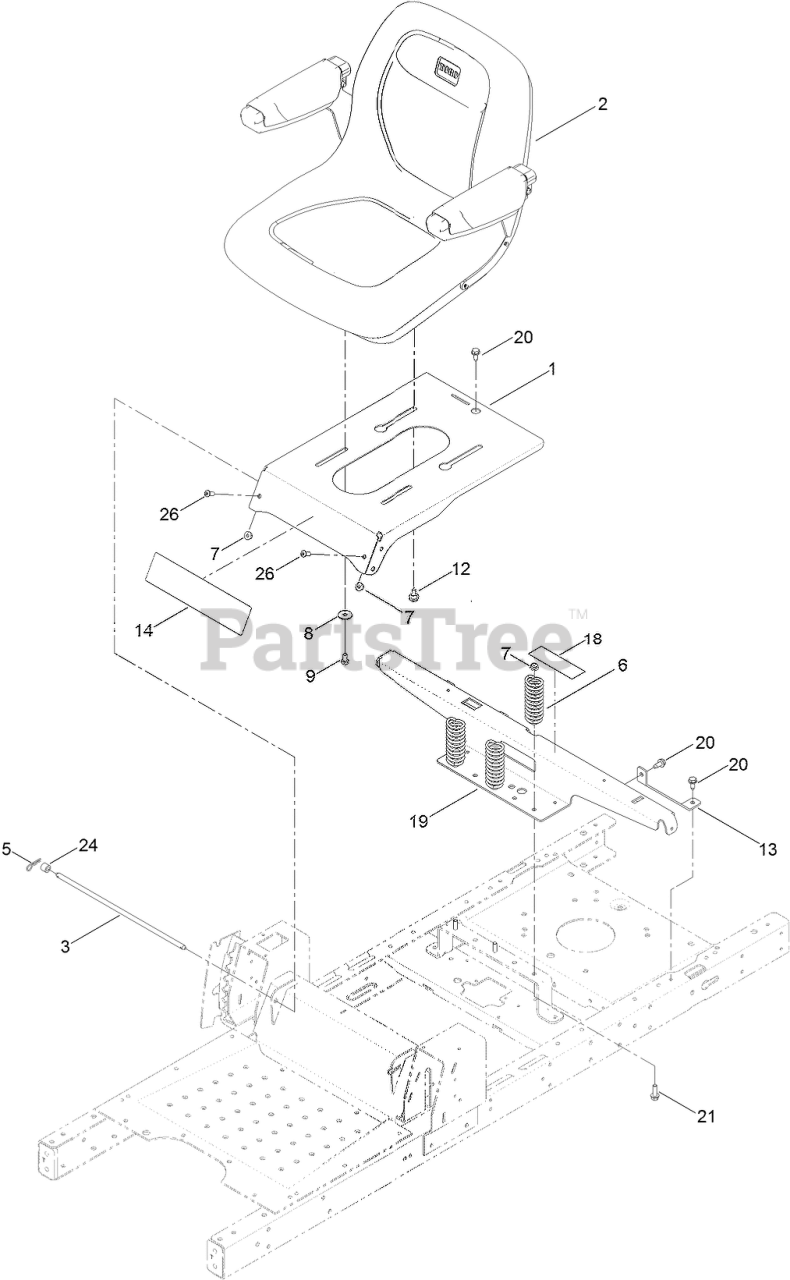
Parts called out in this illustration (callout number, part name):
1	PAN-SEAT
2	SEAT-18 Inch
3	ROD-STOP
5	PIN-COTTER
6	SPRING-COMPRESSION
7	NUT-HF, NI
8	WASHER-PIVOT
9	SCREW-HH
12	BOLT-SHOULDER
13	SUPPORT-TANK, REAR
14	DECAL-TIMECUTTER
18	DECAL-SERVICE, CE
19	SUPPORT-POD, WIDE
20	SCREW-HWHTF
21	SCREW-HHF
24	BUSHING-LEVER, LIFT
26	SCREW-HSBH
